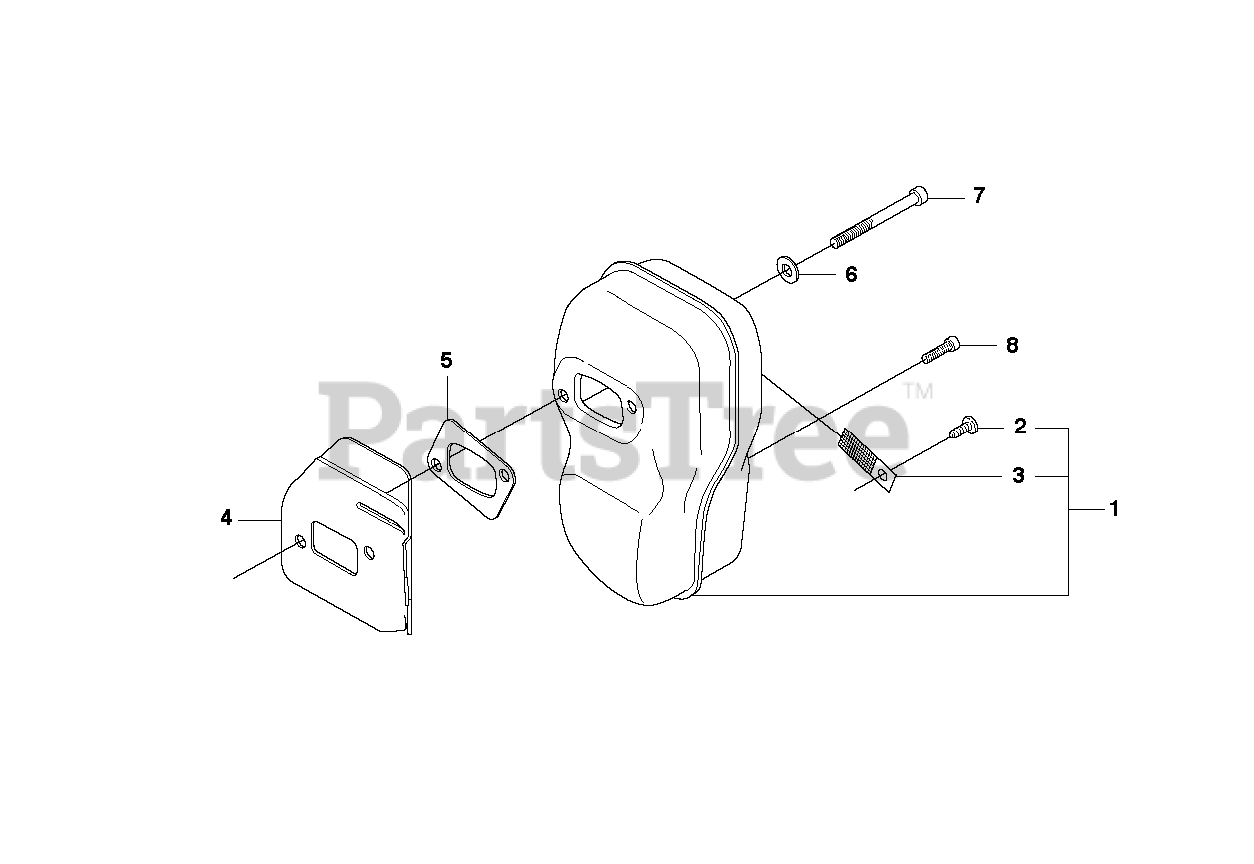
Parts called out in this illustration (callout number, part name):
1	MUFFLER
4	SCREW IHSCFM
6	DOUBLE WASHER
